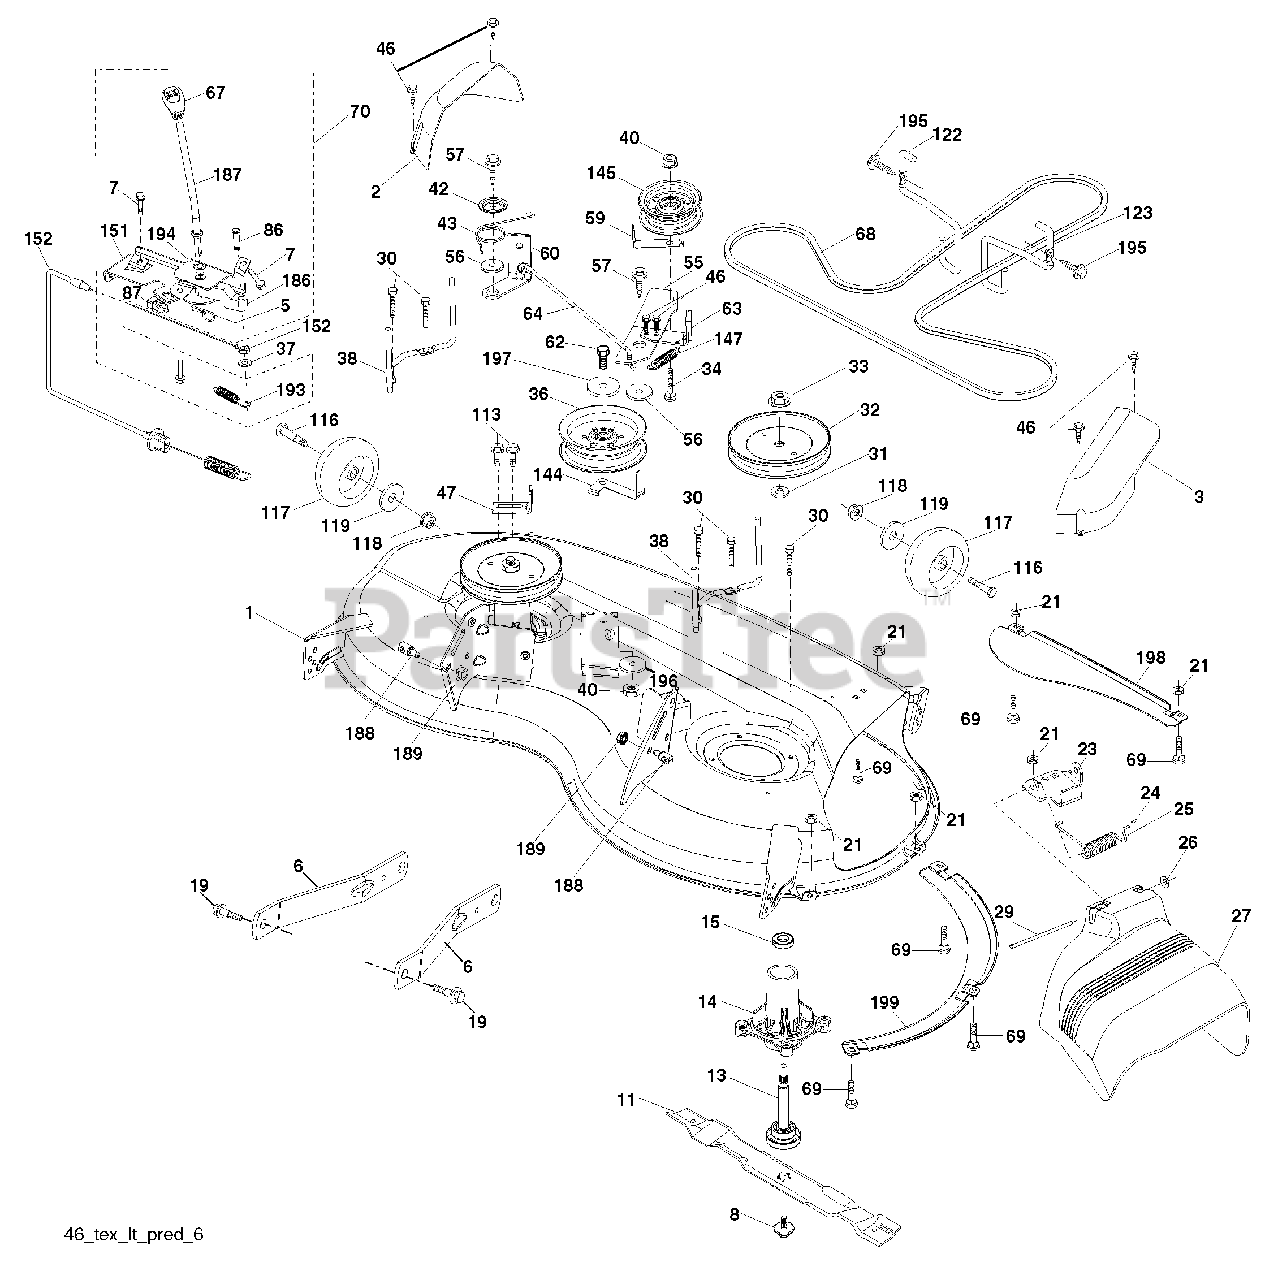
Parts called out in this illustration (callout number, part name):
1	Mower Housing
2	Cover Mandrel
3	Cover Mandrel
5	Retainer Spring
6	Arm Suspension
7	Screw 10 x 3/4 Single Hex
8	Bolt/Washer asm 7/16-20 unf
11	Blade Mower
13	Shaft Assembly, Mandrel
14	Housing, Mandrel
15	Bearing, Ball, Mandrel
19	Bolt, Shoulder
21	Nut
23	Bracket, Deflector
24	Cap, Sleeve
25	Spring, Torsion, Deflector
26	Nut, Push
27	Shield, Deflector
29	Rod, Hinge
30	Screw Thdrol Rolling Wsh Hd
31	Washer, Spacer
32	Pulley, Mandrel
33	Nut, Toplock, Flanged
34	Bolt Carr Sh. 3/8-16 x 1-1/2 Gr. 5
36	Pulley, Idler, Flat
37	Washer 13/32 x 13/16 x 16 Ga.
38	Keeper Belt LH Mandrel
40	Nut, Lock Flg. 3/8-16 unc
42	Spring Trosion Brake
43	Spring Torsion Retainer
46	Screw
47	Bracket Clutch Cable
55	Arm, Idler
56	Spacer, Retainer
57	Screw Hexwsh Thd 3/8-16 x 1
59	Guard, Tuv Idler (94)
60	Arm Brake Mower
62	Bolt Fin Hex 3/8-16 x 2-1/4 Gr. 5
63	Arm Brake Mower
64	Linkage Brake
67	Handle, Clutch Cable
68	V-Belt
69	Bolt
70	Clutch Asm. Manual
86	Pin Attachment Cable
87	Switch Interlock
113	Screw 5/16-18
116	Bolt, Shoulder
117	Wheel, Gauge
118	Nut, Centerlock 3/8-16
119	Washer 3/8 x 7/8 x 14 Ga.
122	Keeper Belt Eng. LH
123	Keeper Belt Eng. RH
144	Keeper Belt
145	Pulley Idler
147	Spring Return
151	Bracket Clutch CBL
152	Cable Clutch Manual w/Spr.
186	Arm Acutator CL Cable
187	Lever Control CL Cable
188	Stud Fastener
189	Nut Lock Hex Flange
193	Spring Plunger Actuator
194	Bearing Control Lever Clutch
195	Screw Hexwsh Thdrol 3/8-16 x 3/4
196	Washer 13/32 x 2 x 10 Ga
197	Washer 13/32 x 13/16 x 12 Ga.
198	Baffle Center Front
199	Baffle Front RH
199	Mandrel Assembly
199	Replacement Mower, Complete
